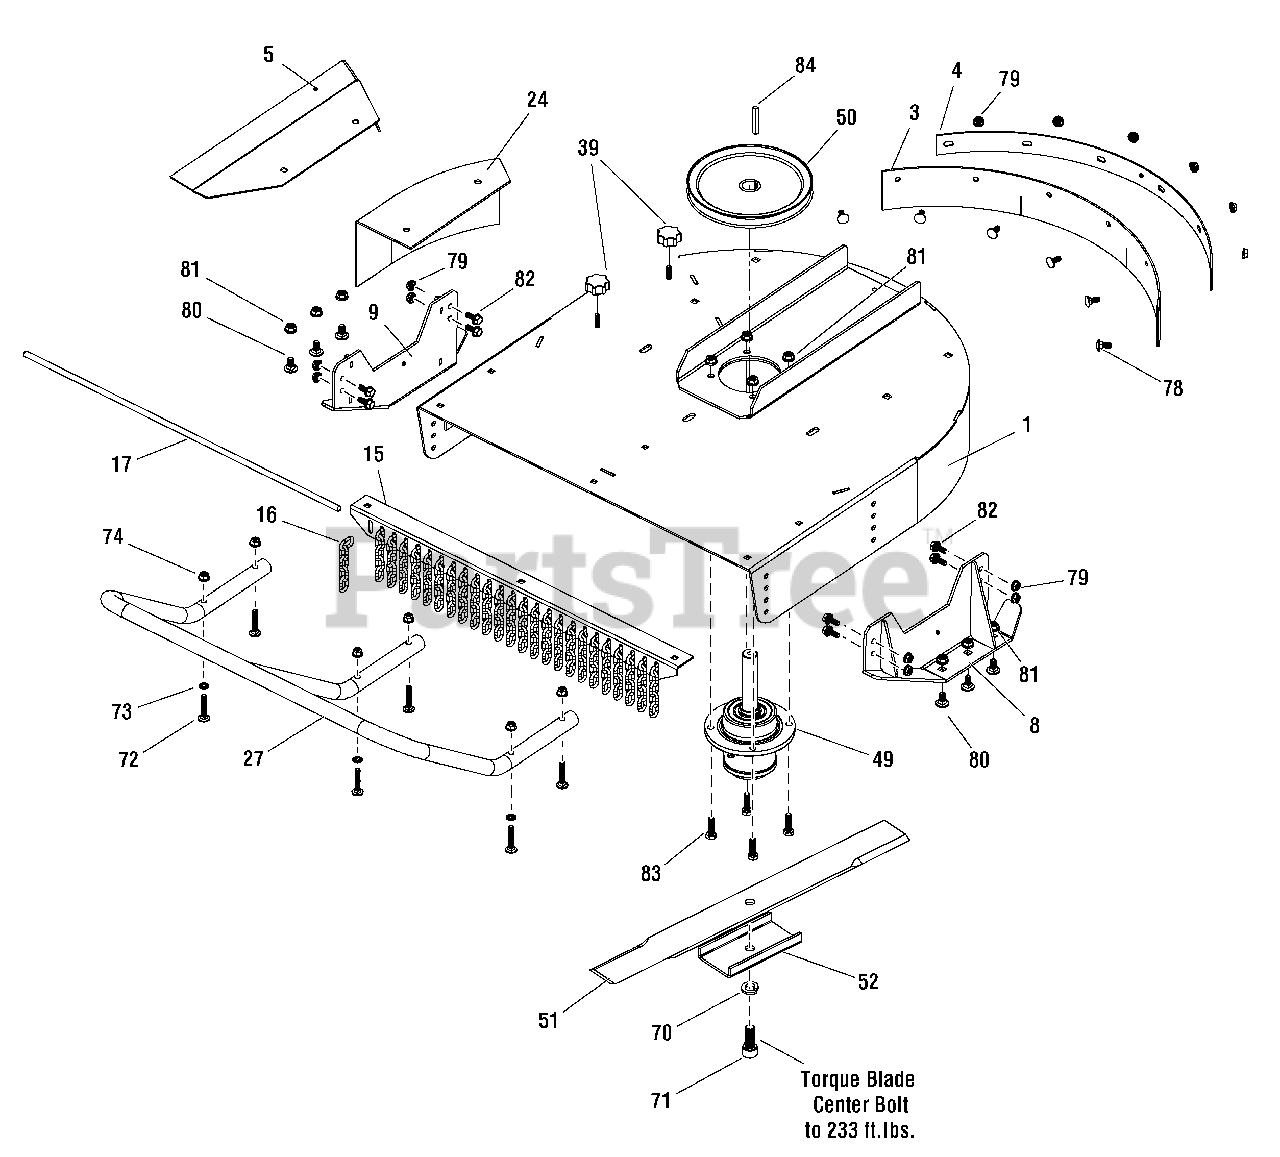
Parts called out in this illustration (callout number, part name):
1	MOWER DECK, 25"
3	REAR DEFLECTOR
4	BACKING STRIP
5	DEFLECTOR, DISCHARGE
8	SKI, LEFT
9	SKI, RIGHT
15	HANGER, CHAIN CURTAIN
16	SAFETY CHAIN
17	RETAINER, CHAIN CURTAIN
24	MULCHING COVER
27	FRONT PUSH BAR
39	HAND KNOB, 5/16"-18 X 11/16"
49	SPINDLE ASSEMBLY, CUTTING BLADE
50	PULLEY, MOWER DECK, 8"
51	BLADE, 25"
52	BLADE CLAMP
70	WASHER, LOCK, HIGH COLLAR SPLIT, 5/8"
71	BOLT, 5/8"-11 X 1-1 / 2" SHCS
72	BOLT, 5/16"-18 X 1-3/4" CARRIAGE
73	PUSH NUT BOLT RETAINER, 5/16
74	NUT, 5/16"-18 HEX FLANGED NYLOK
78	CARRIAGE BOLT, 5/16-18 X 3/ 4"
79	HEX NUT, SERRATED, 5/16-18
80	CARRIAGE BOLT, 3/8"-16 x 3/4"
81	FLANGED LOCK NUT, 3/8"-16
82	BOLT, 5/16"-18 X 3/4"
83	BOLT. 3/8"-16 X 1-1/4" HEAVY HEX
84	KEY, 1/4" X 1/4" X 2"
